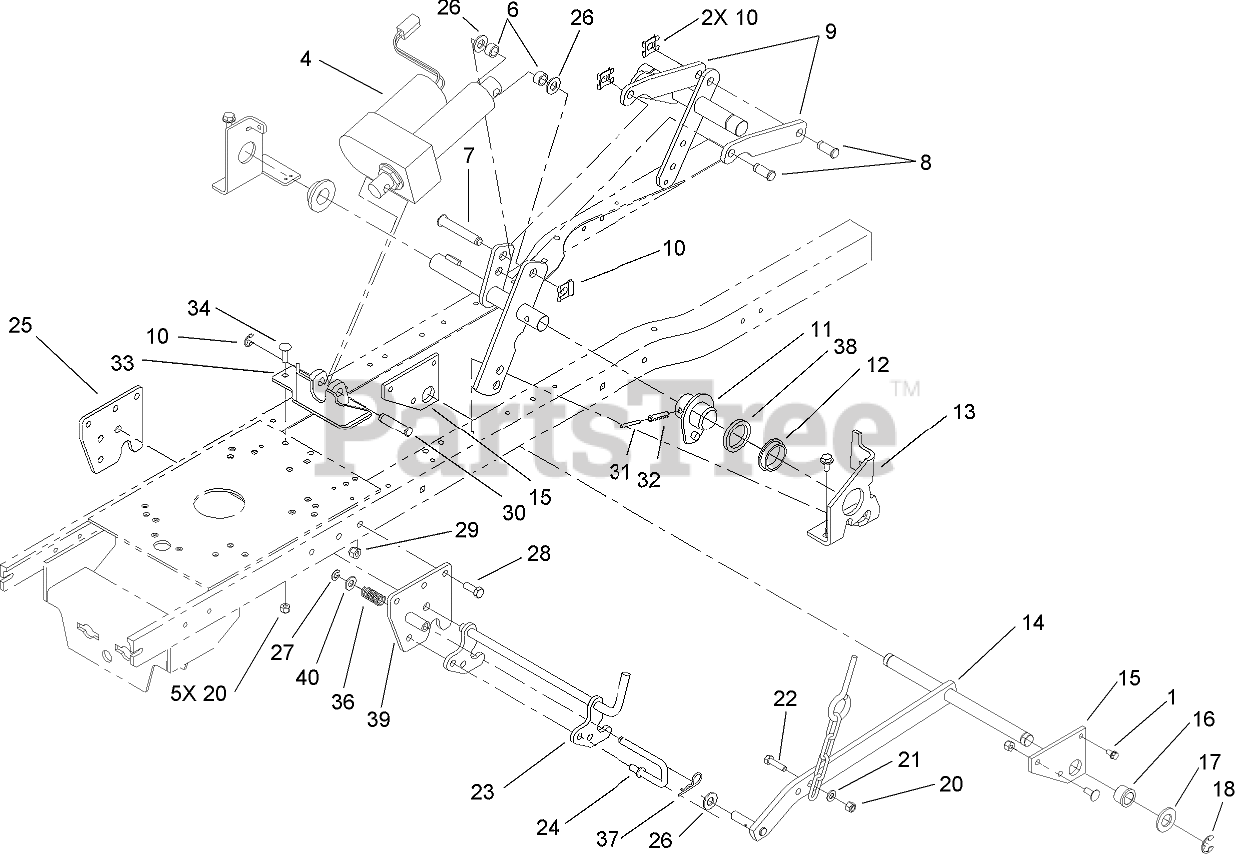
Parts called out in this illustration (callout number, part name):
1	SCREW-HWHTF
4	ACTUATOR
6	SPACER
7	PIN-CLEVIS
8	PIN-CLEVIS
9	STRAP-LINK, LIFT
10	CLIP-PIN
11	END CAP ASM
12	BUSHING
13	BRACKET-ARM, LIFT
14	LIFT BAR ASM
15	Plate-Lift, Rear
16	BUSHING-FLANGE
17	WASHER-FLAT
18	E-RING
20	NUT-LOCK, NI
21	WASHER-PLAIN
22	SCREW-HH
23	MIDHITCH LATCH ASM
24	ROD-CATCH
25	Plate-Hitch
26	WASHER-FLAT
27	RING-RETAINING
28	SCREW-HH
29	NUT-LOCK, NI
30	PIN-CLEVIS
31	PIN-SPRING
32	PIN-ROLL
33	ACTUATOR BRACKET ASM
34	SCREW-CARR
36	SPRING-COMPRESSION
37	PIN-HAIR
38	SPACER
39	MIDHITCH ASM
40	WASHER-FLAT
